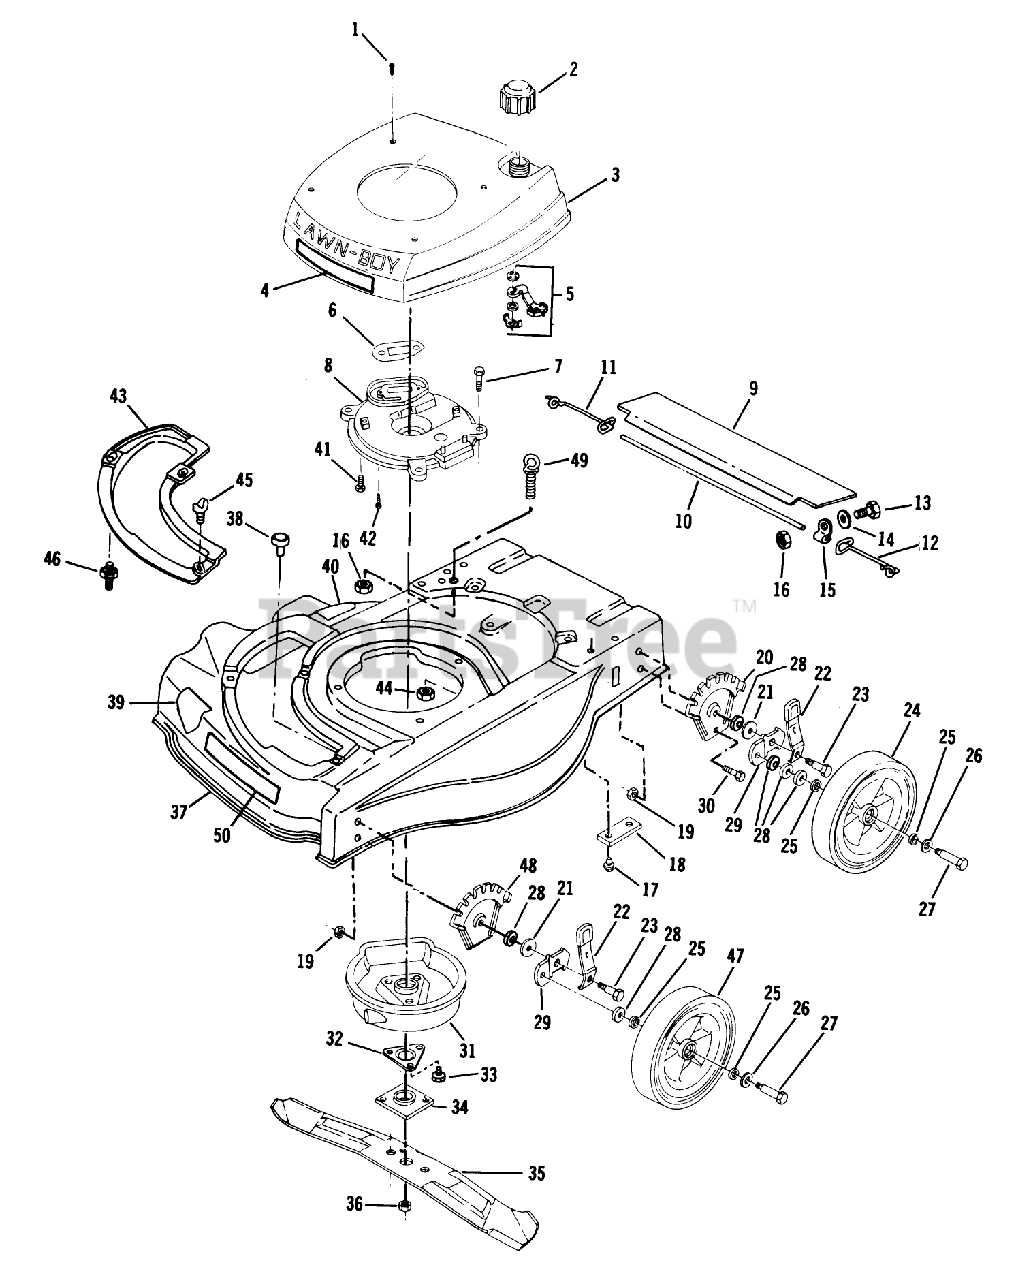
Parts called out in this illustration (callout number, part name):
1	SCREW LAWRENCE
2	FUEL CAP & INSERT
7	SCREW-HH
8	PLATE,MUFFLER F
10	ROD T/SHIELD ADV WIRE
11	SPRING;TRAILING SHIELD RH
12	SPRIG T/SHLD ASOC
14	WASHER F
15	CLAMP ROD KMC
16	LOCKNUT E
17	SCREW
19	LOCKNUT
21	WASHER
22	KNOB & SPRING
23	BOLT
25	WASHER
26	SPACER
27	BOLT WHEEL
28	WASHER WROUGHT
32	SUPPORT F
33	SCREW
34	PLATE AND COLLAR ASM
36	NUT-BLADE
42	SCREW V
44	NUT-LOCK F
45	WING SCREW LAWRE
47	WHEEL & TIRE KIT
48	PLATE HGT ADJ TRO
49	BOLT-EYE
